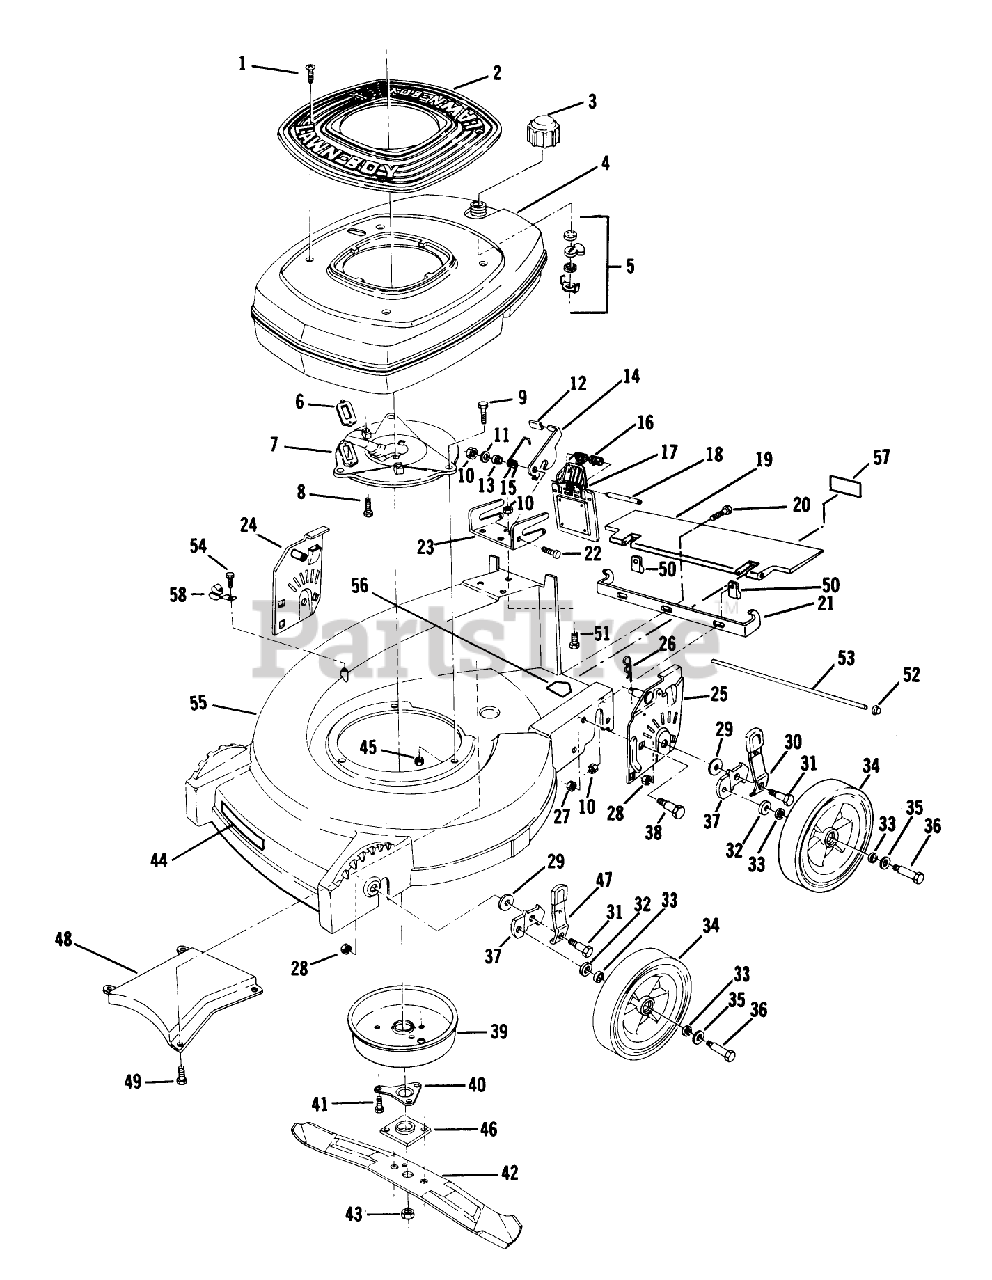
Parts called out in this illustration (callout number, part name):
1	SCREW - SELF TAPPING
3	FUEL CAP & INSERT
5	SHUT-OFF VALVE S
8	SCREW V
9	SCREW-HH
10	LOCKNUT E
15	SPRING
16	SPRING ASOC
18	ROD (RB&W)
19	T/SHIELD SM&P
25	HANDLE BRACKET LH
26	HAIR PIN
27	NUT-LOCK F
28	LOCKNUT
29	WASHER
31	BOLT
32	WASHER WROUGHT
33	WASHER
35	SPACER
36	BOLT WHEEL
39	MUFFLER COVER F
40	SUPPORT F
41	SCREW
43	NUT-BLADE
45	NUT-LOCK F
46	PLATE AND COLLAR ASM
48	BAFFLE CHUTE PL
54	SCREW LAWRENCE
